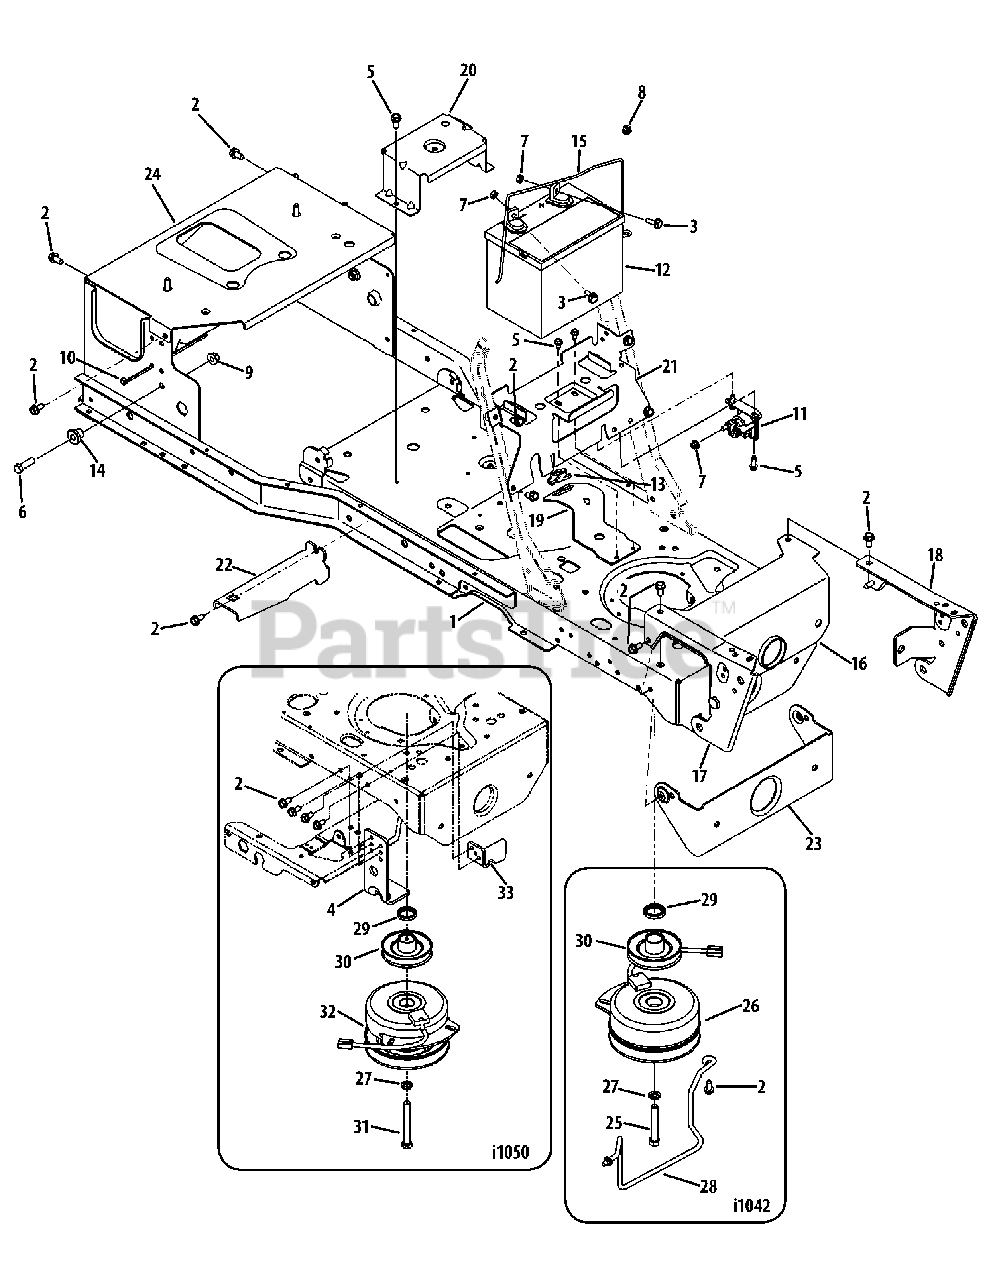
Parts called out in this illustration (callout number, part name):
1	Frame Assembly
2	Hex Washer Screw, 5/16-18 x .75
3	Hex Flange Screw, 1/4-20 x .75
4	Up Stop Deck Bracket
5	Hex Washer Screw, 1/4-20 x .75
6	Hex Cap Screw, 3/8-16 x 1.25
7	Sems Nut, 1/4-20
8	Hex Flange Lock Nut, 1/4-20
9	Hex Flange Lock Nut, 3/8-16
10	Cable Tie
11	Solenoid
13	Steering Shaft Bushing
14	Shoulder Spacer, .38 x 1.0 x .7
15	Battery Strap
16	Pivot Bar Bracket
17	RH Pivot Support Bracket
18	LH Pivot Support Bracket
19	Steering Support Bracket
20	Support Fender Bracket
21	Battery Support Bracket
22	Running Board Support Bracket
23	Pivot Bar Support Bracket
24	Seat Frame Plate
25	Hex Lock Screw, 7/16-50 x 2.75
26	Electric PTO Clutch, 42" Deck
27	Lock Washer, 7/16
28	Belt Keeper Rod
29	Spacer, 1.375 x 1.00 x .25
30	Engine Pulley
31	Hex Lock Screw, 7/16-50 x 3.50
32	Electric PTO Clutch, 50" Deck
33	Clutch Bracket
